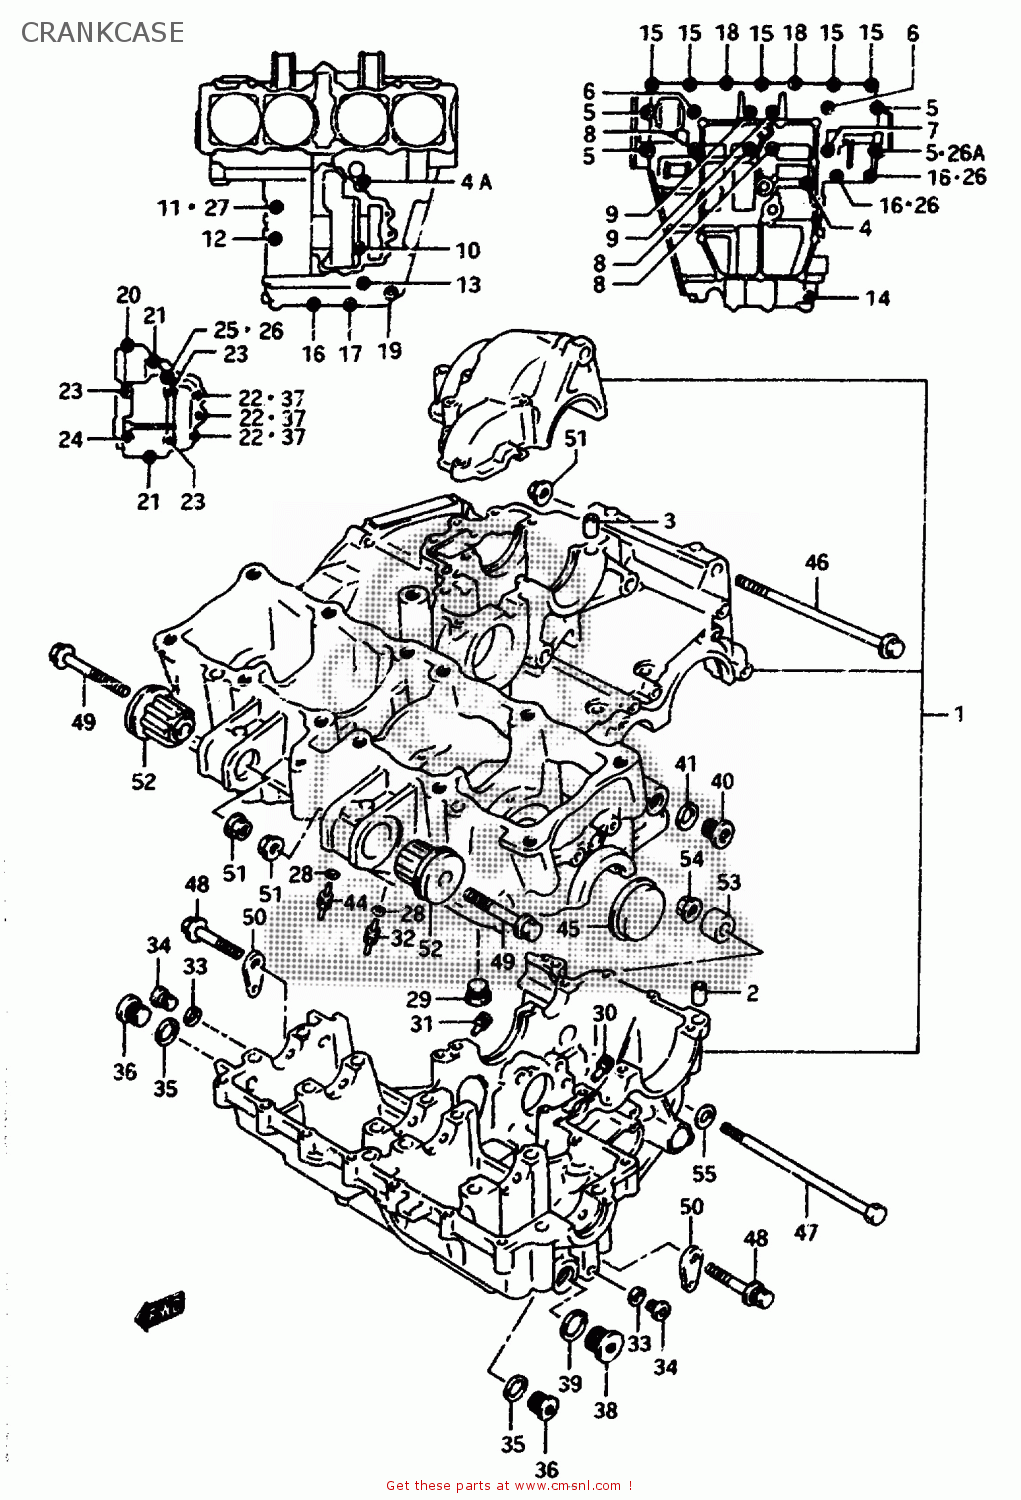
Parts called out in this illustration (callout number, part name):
1	CRANKCASE SET
2	PIN(10.4X13X22)
3	PIN
4	BOLT(6X105)
4A	BOLT(6X105)
5	BOLT 9X80
6	BOLT(9X95)
7	BOLT(9X105)
8	BOLT(9X115)
9	BOLT(9X60)
10	BOLT
11	BOLT
12	BOLT
13	BOLT
14	BOLT
15	BOLT
16	BOLT
17	BOLT
18	BOLT
19	BOLT
20	BOLT
21	BOLT
22	BOLT
23	BOLT
24	BOLT
25	BOLT(6X145)
26	GASKET(6.2X13X1.2) (NAS)
26A	GASKET(10.2X20X2).3 (NAS)
27	GASKET(8.2X14X1) (NAS)
28	O RING(D:1.2,ID:4)
29	PLUG,CRANKCASE,UPPER
30	JET
31	JET(140)
32	JET(13)
33	GASKET(10X14X3.6) (NAS)
34	PLUG(10X6.8)
35	GASKET(16X22X2) (NAS)
36	PLUG
37	GASKET(5.8X11X1.2) (NAS)
38	PLUG,22X11
39	GASKET(22X27X2) (NAS)
40	PLUG
41	GASKET(13.8X18.8X4.8) (NAS)
42	BEARING,CRANK THRUST(GREEN)
43	BEARING,CRANK THRUST(BLUE)
44	JET(13)
45	PLUG
46	BOLT 10X150
47	BOLT,ENGINE MOUNTING,REAR,LOWER
48	BOLT
49	BOLT
50	NUT,ENGINE MOUNT,LOWER
51	NUT
52	BUSH,ENGINE MOUNTING
53	SPACER,ENGINE MOUNT (L:13)
54	NUT 12MM
55	WASHER
